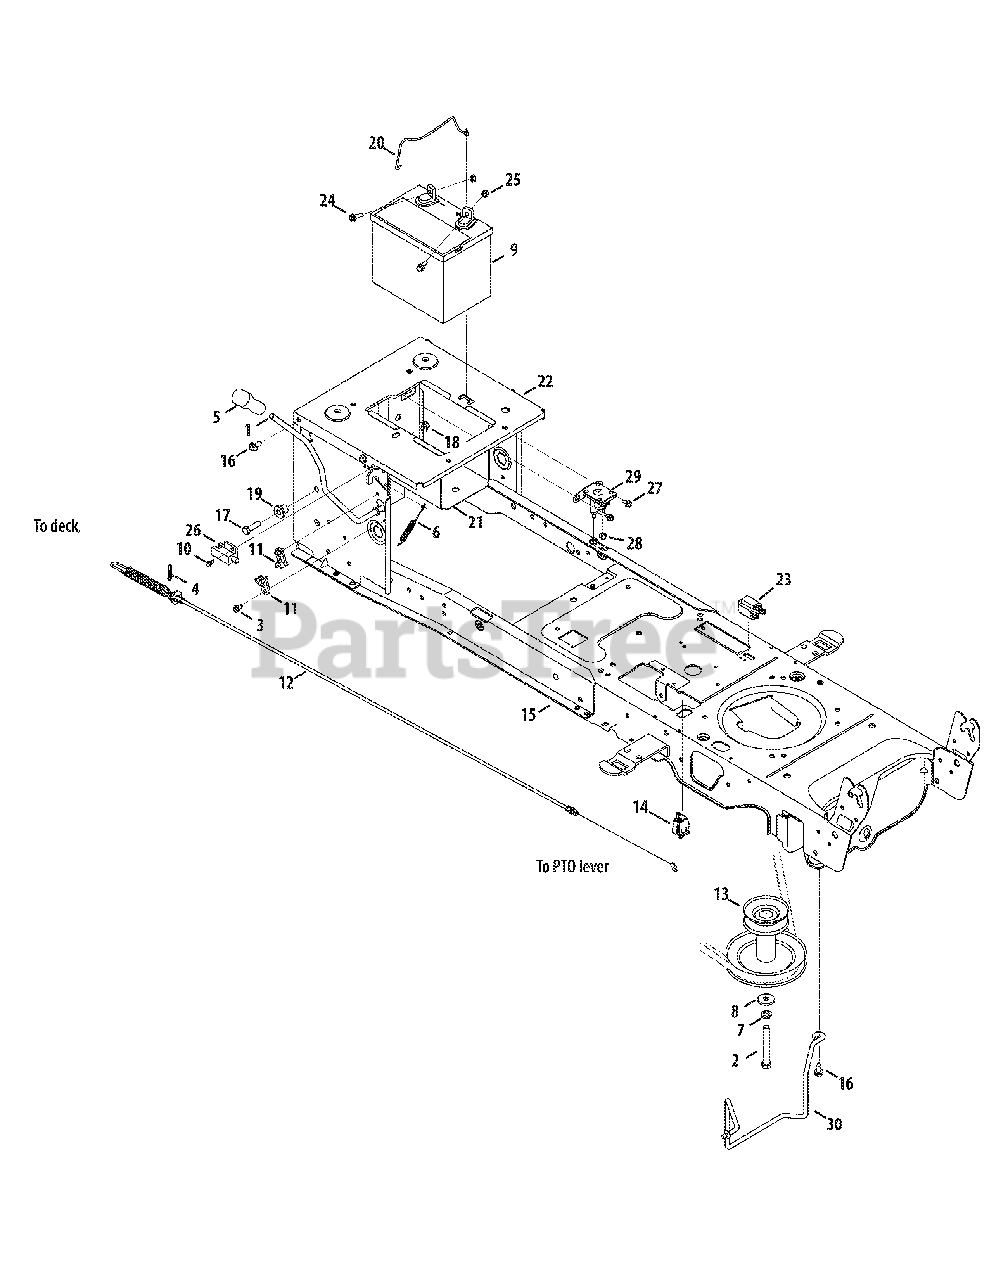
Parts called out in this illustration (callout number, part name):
1	Handle Ass’y , PTO
2	Hex Screw 7/16-20 x 3.5 Gr. 5
3	Hex Wash S-Tapp Scr 1/4-20 x .50
4	Bow-Tie Cotter Pin
5	Handle Grip 3/8
6	Extension Spring .38 Dia. x 5.6
7	Lockwasher 7/16 ID
8	Flat Washer .450 x 1.25 x .164
9	Battery 245 CCA (Dry)
10	Shoulder Screw #10-32 x .50
12	Deck Engagement Cable
13	Engine Pulley 3.39 x 6.12 Dia.
14	Switch, Plunger, snap mount
15	Lower Frame Ass’y
16	Hex Wash Hd. Tapp Scr. 5/16-18 x .75
17	Hex Bolt 3/8-16 x 1.25
18	Flange Lock-Nut 3/8-16 Gr. F Nylon
19	Shoulder Spacer .38 x 1.0 x .70
20	Battery Retainer Rod
22	Seat Frame Bracket
23	Switch, 3-Pole, (NC-NO-NO)-Brake
24	Hex Hd. Flg. Scr. 1/4-20 x .75 Gr. 5
25	Sems Hex Nut 1/4-20
26	Switch, Interlock
27	Hex Wash HD Tapp Scr 1/4-20 x .375
28	Hex L-Flanged Nut 1/4-20 Gr. F Nylon
29	Solenoid
30	Belt Keeper Rod
